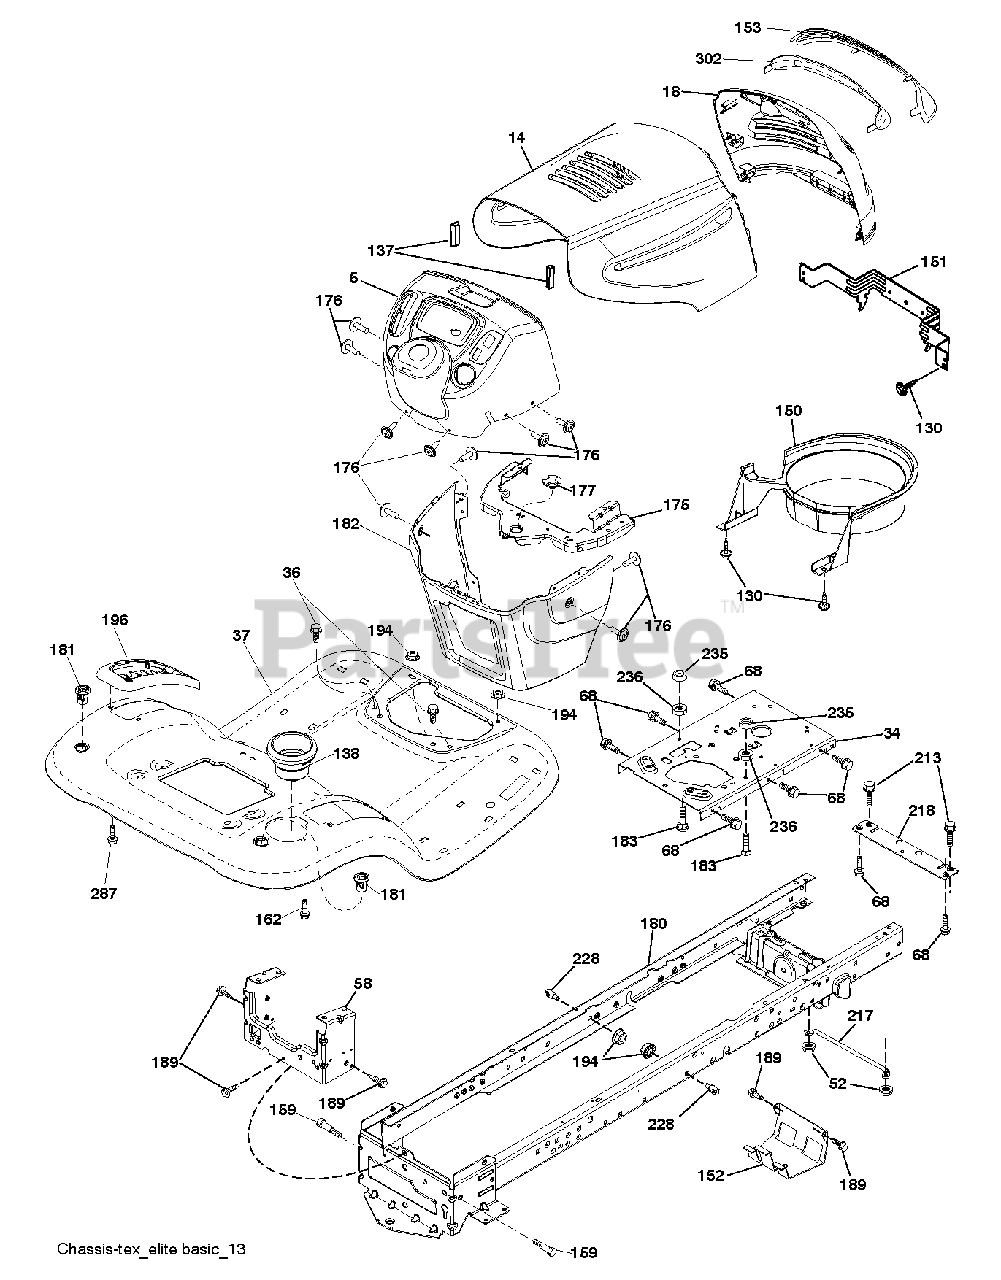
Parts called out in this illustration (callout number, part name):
5	DASH.P/L.TEX.CBL.CL.N/CHK.BLAC
14	HOOD.STEEL.ELITE.YELLOW
18	GRILLE.ELITE.BASIC.LT.BLACK
34	PLATE.ENGINE.WELDED.CHASSIS
36	SCREW 5/16"
52	LOCKNUT
58	DRAWBAR UPPER 2PC SMALL FENDER
68	SCREW LT
130	SCREW.#10 X 0.750.BOS (2 2)
137	BUMPER.HOOD.LARGE.1.75"
138	CUPHOLDER.TL.TEX.BLACK
150	DUCT.INTAKE.AIR.KAW
151	BRACKET PIVOT
152	SHIELD.BROWNING.W/TEX
153	LENS.GRILLE.BASIC.BAR.LT.CLR
159	SCREW, 3/8-16X3/4
162	SCREW.HI-LO.CONSOLE
175	CROSSMEMBER.LT
176	SCREW.#10-24X5/8.RN.QU
177	BUSHING STEERING
180	CHASS.WLDMNT.TL.12GA/2P.48/54
181	FEND/FTRST.PCH.CPH.NFW
182	DASH.LOWER.LT.CCS
183	BOLT.5/16-18X1-1/4 FULL THD
189	SCREW
194	NUT LOCK HEX FLANGE 5/16-18
196	CONSOLE.ASM.DECKLFT.BL/RBT.TLT
213	BOLT
217	ROD.PIVOT.HOOD
218	X-PIECE.HOOD.STOP.NON/
228	STUD.FASTNER.W/ANTI-ROTATE
235	SPACER FENDER
236	NUT.CENTERLOCK.5/16-
287	SCREW 1/4X20
302	INSERT.LENS.REFLECTIVE.LEFT
